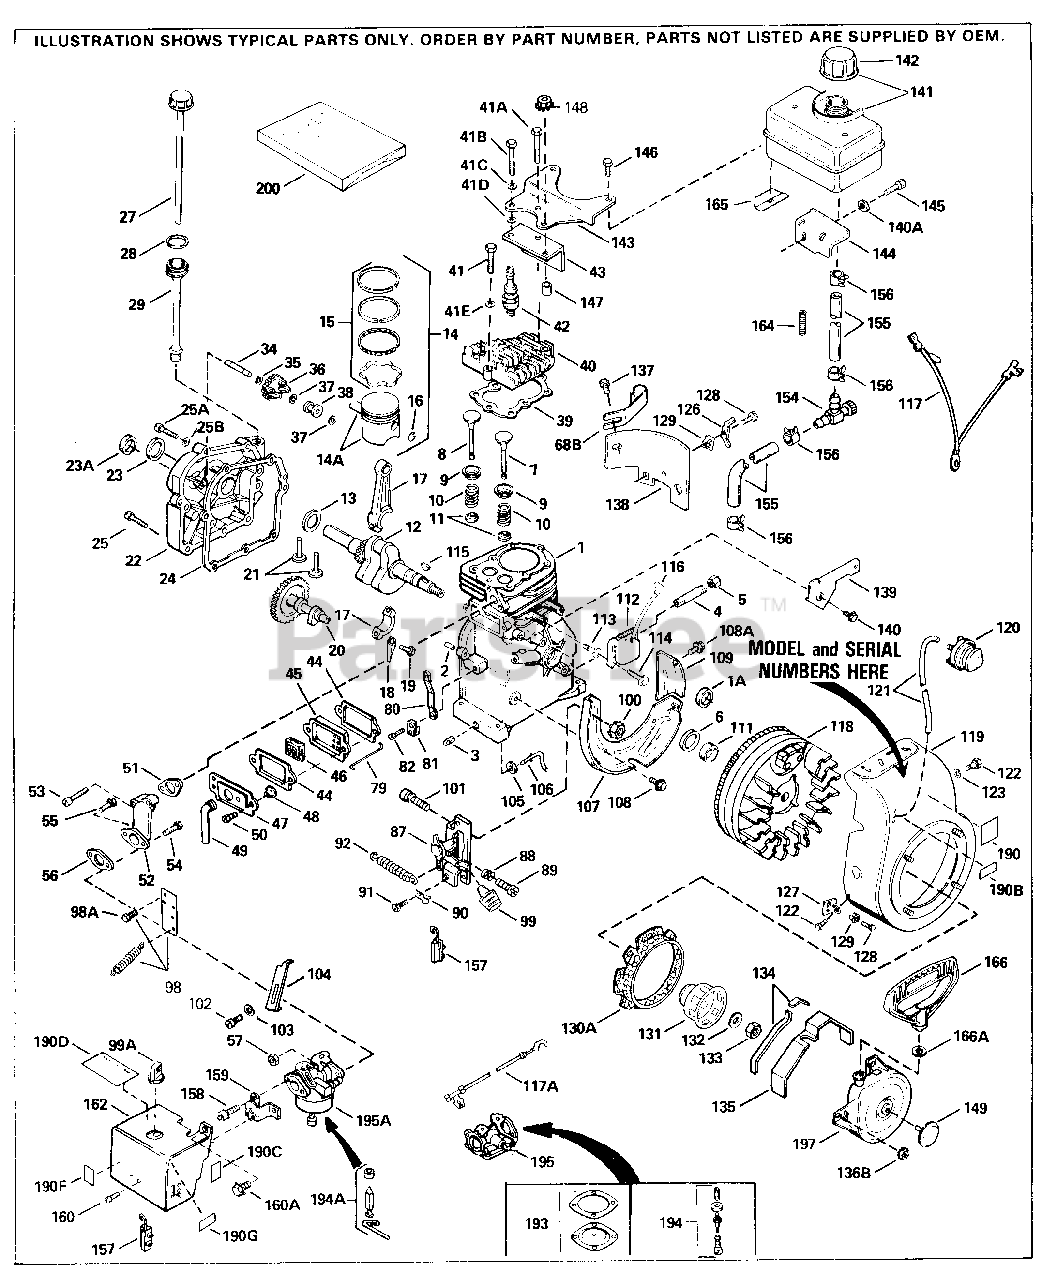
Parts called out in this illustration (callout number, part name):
1	"Cylinder (Incl. 2, 3 & 6) 2-1/2" Bor e
2	Dowel Pin
3	Oil Drain Plug (Sq. hd., 1/4-18)
6	Seal, Oil
7	Intake Valve (Std.) (Incl. 151)
7	Exhaust Valve (1/32" OS) (Incl. 151)
8	Exhaust Valve (Std.) (Incl. 151)
8	Exhaust Valve (1/32" OS) (Incl. 151)
9	Valve Spring Cap Used in early produc tion
10	Spring, Valve
11	Valve Spring Cap
12	Crankshaft
13	Washer, Thrust
14	Piston, Pin & Ring Set (Std.) 2-1/2" Bore
14	Piston, Pin & Ring Set (.010" OS)
14	Piston, Pin & Ring Set (.020" OS)
14A	Piston & Pin Ass'y. (Std.)(2-1/2") In c l.16
14A	Piston & Pin Ass'y. (.010" OS) Incl. 16
14A	Piston & Pin Ass'y. (.020" OS) Incl. 16
15	Ring Set (Std.)
15	Ring Set (.010" OS)
15	Ring Set (.020" OS)
16	Piston Pin Retaining Ring
17	Rod Assy., Connecting (Incl. 18 & 19)
18	Dipper, Oil
19	Bolt, Connecting rod
20	Camshaft
21	Valve Lifter
22	Cover, Cylinder (Incl. 23, 23A & 34)
23	Oil Seal
23A	Camshaft Seal
24	* Gasket, Cylinder cover
25	Screw, 1/4-20 x 1-1/4"
27	Dipstick, Oil (Incl. 28)
28	"O" Ring
29	Tube, Oil fill
34	Shaft, Mechanical governor
35	WASHER
36	Gear Assy., Governor (Incl. 35)
37	Retaining Ring
38	Spool, Governor
39	* Gasket, Cylinder head
40	Head, Cylinder (Incl. 41A)
41	Screw, 5/16-18 x 1-1/2" Use as requir ed
41	Screw, 5/16-18 x 2-1/4" Use as requir ed
41	Screw, 5/16-18 x 2" (Use as required)
41A	Screw, 5/16-18 x 2" (Use as required)
42	Resistor Spark Plug - RJ17LM
43	Baffle, Heat
44	* Gasket, Breather (One required)
45	Breather Assy. (Incl. 44 & 46)
46	Element, Breather
50	Screw, 10-24 x 1/2"
51	* Gasket, Intake to cylinder
52	Intake Pipe
53	Screw, 1/4-20 x 1-19/32"
54	Screw, 1/4-20 x 1-7/32"
55	Screw, 1/4-28 x 7/8"
56	* Gasket, Carburetor to intake
57	Nut & Lock Washer 1/4-28
68B	Fill Tube Clip
79	Link, Throttle
80	Lever, Governor
81	Clamp, Governor lever
82	Screw, 8-32 x 5/16"
87	Control Bracket (Incl. 88,89,100,101 & 157) NOTE: In original productio n the speed control assembly is rivet ed to the blower housing baffle (Ref. #107). Replacement speed control as sembly includes screws (Ref. #101)and nuts (Ref. #100) for mou
88	Spring, Compression
89	Screw, 5-40 x 7/16"
92	Spring, Extension
98	Spring Assy., Extension (Incl. 98A)
99	Control Knob
99A	Control Knob
100	Lock Nut, 8-32
101	Screw, 10-24 x 9/16"
101	Screw, 8-32 x 1/2" (Use as required)
101	Screw, 8-32 x 3/8" (Use as required)
105	Flat Washer
106	Rod, Governor
107	Baffle, Blower housing
108	Screw, 1/4-20 x 5/8"
108A	Screw, 8-18 x 7/16"
109	Baffle, Extension
111	Spacer, Flywheel key
112	Solid State Ass'y.
113	Stud, Solid State mounting
114	Screw, Torx T-15, 10-24 x 1"
115	Flywheel Key (also available in Packa ged Part #740007B)
116	Cover, Spark plug (Use as required)
117	Ground Wire
118	Flywheel (w/ring gear)
119	Housing, Blower NOTE: In original pr oduction, the starter may be riveted to theblower housing. If the starter or blower housing needs replacement, the other may need holes used for po p rivetingenlarged to use standard mo unting hardware. Order 4
120	Primer Assy.
121	Line, Primer
122	Screw, 1/4-28 x 7/16"
127	Bracket, Grommet mounting
128	Screw, 8-32 x 3/8"
129	Breather Tube Grommet
130A	Screen, Starter
131	Cup, Starter
132	Washer, Belleville
133	Nut, Flywheel
134	Seal, Snow guard
135	Guard, Starter
136B	Nut & Lock Washer 1/4-28
137	Screw, 10-24 x 1/2"
138	Blower Housing Extension
139	Bracket, Hold down
140	Screw, 10-24 x 9/16"
140A	Washer, Flat
141	Fuel Tank (Incl. 142 & 156)
142	Fuel Cap (Red 1-1/2" ID) also availab le in Packaged Part #740005B
142	Cap, Fuel filler
142	Cap, Fuel filler (Std.) Use as requir ed
143	Fuel Tank Bracket
144	Fuel Tank Bracket
145	Screw, 1/4-20 x 11/16"
146	Screw, 1/4-15 x 7/8"
147	Spacer models)
154	Valve, Shut-off
155	Fuel Line (8.62") equired)
155	Fuel Line (Braided, 16") Use as requi red
156	Fuel Line Clamp
157	Terminal Ass'y. (Use as required)
158	Screw, 10-32 x 1/2"
159	Bracket, Choke
160	Screw, 10-32 x 1/2"
160A	Screw, 8-32 x 5/16"
162	Cover, Carburetor
166	Starter Handle (Mitten Grip) also ava ilable in Packaged Part #740053B
166A	Washer, Flat
190	Decal, Instruction
190B	Decal, Primer
190C	Decal, Instruction
190D	Decal, Choke
190F	Throttle Decal
194A	Inlet Needle Seat & Clip Assy.
195A	Carburetor (Incl. 56) (Refer to Divis ion 5, Section A, page 198 for breakd own)
197	Starter, Rewind Refer to Division 5, Section C, page 29 for breakdown
200	* Gasket Set (Incl. items marked *)
